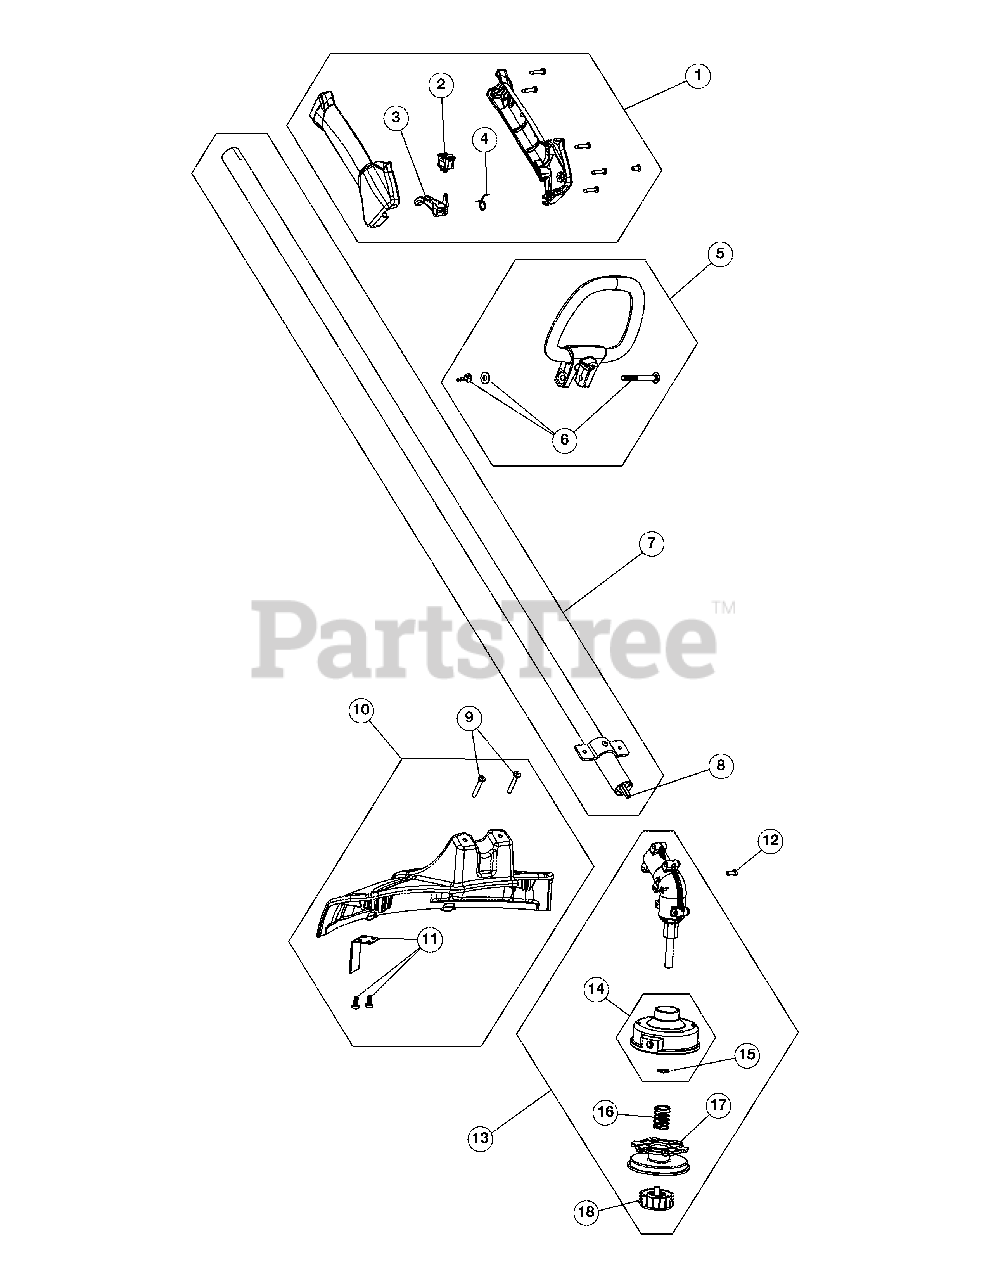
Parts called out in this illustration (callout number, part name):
1	Throttle Housing Assembly (Incl. 2-4)
3	Throttle Trigger
4	Throttle Trigger Spring
5	D-Handle (Incl. 6)
6	D-Handle Hardware Assembly
7	Drive Shaft Housing Assembly (Incl. 8)
8	Flexible Drive Shaft
9	Shield Mounting Screw
10	Shield Assembly (Incl. 9 & 11)
11	Blade Assembly
12	Anti-Rotation Screw
13	Gearbox Assembly (Incl. 14-18)
14	Outer Spool Assembly (Incl. 15)
15	Retainer
17	Inner Reel
18	Bump Head Knob Assembly
